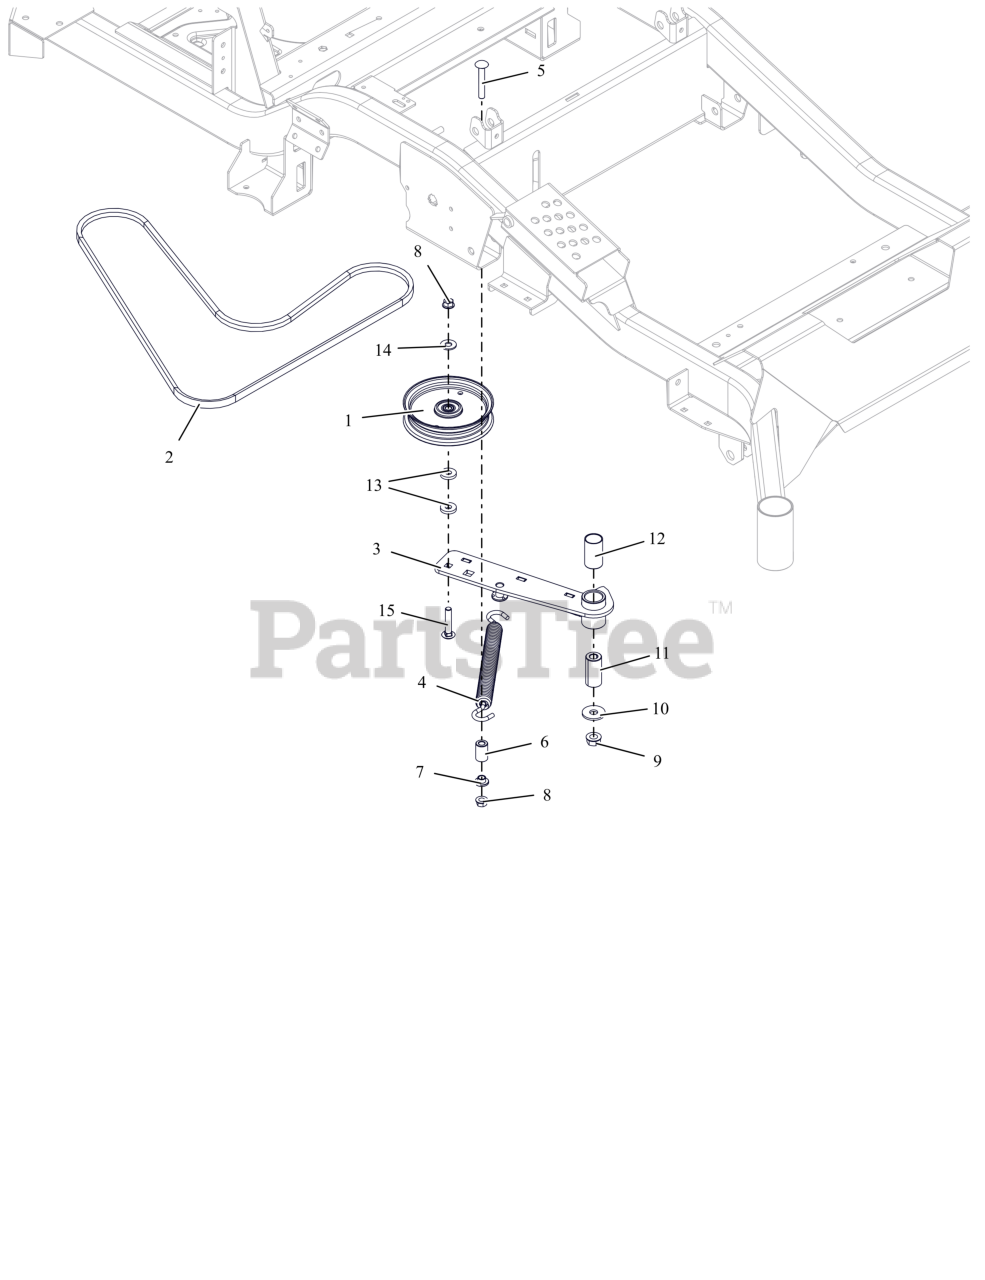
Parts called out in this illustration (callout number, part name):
1	IDLER- FLAT - 5.00" X .75"
2	V-BELT, 4L-WRAPPED
3	WLDMT, HYDRO DRIVE IDLER ARM (BLACK)
4	SPRING, EXTENSION
5	BLT, RHSSN.38-16X2.50 G5 ZCC
6	BUSHING, SLV .380X.750X1.190
7	BSHG-FLG .385X.500X.875X.406
8	NUT-LK-TOP-FLG .38-16 ZC120
9	NUT-LK-TOP-FLG .500-13 GF ZCC
10	WSHR-FL-STL.511X1.44X.125ZC120
11	BSHG, SPCR .502X.997X2.03 PM
12	BSHG, 1.00X1.125X1.937
13	WSHR, FLT .406X1.00X.188 ZCC
14	WSHR,FLT .438X1.00X.083 ZCC
15	BLT, RHSN .38-16X2.00 G5 ZCC
